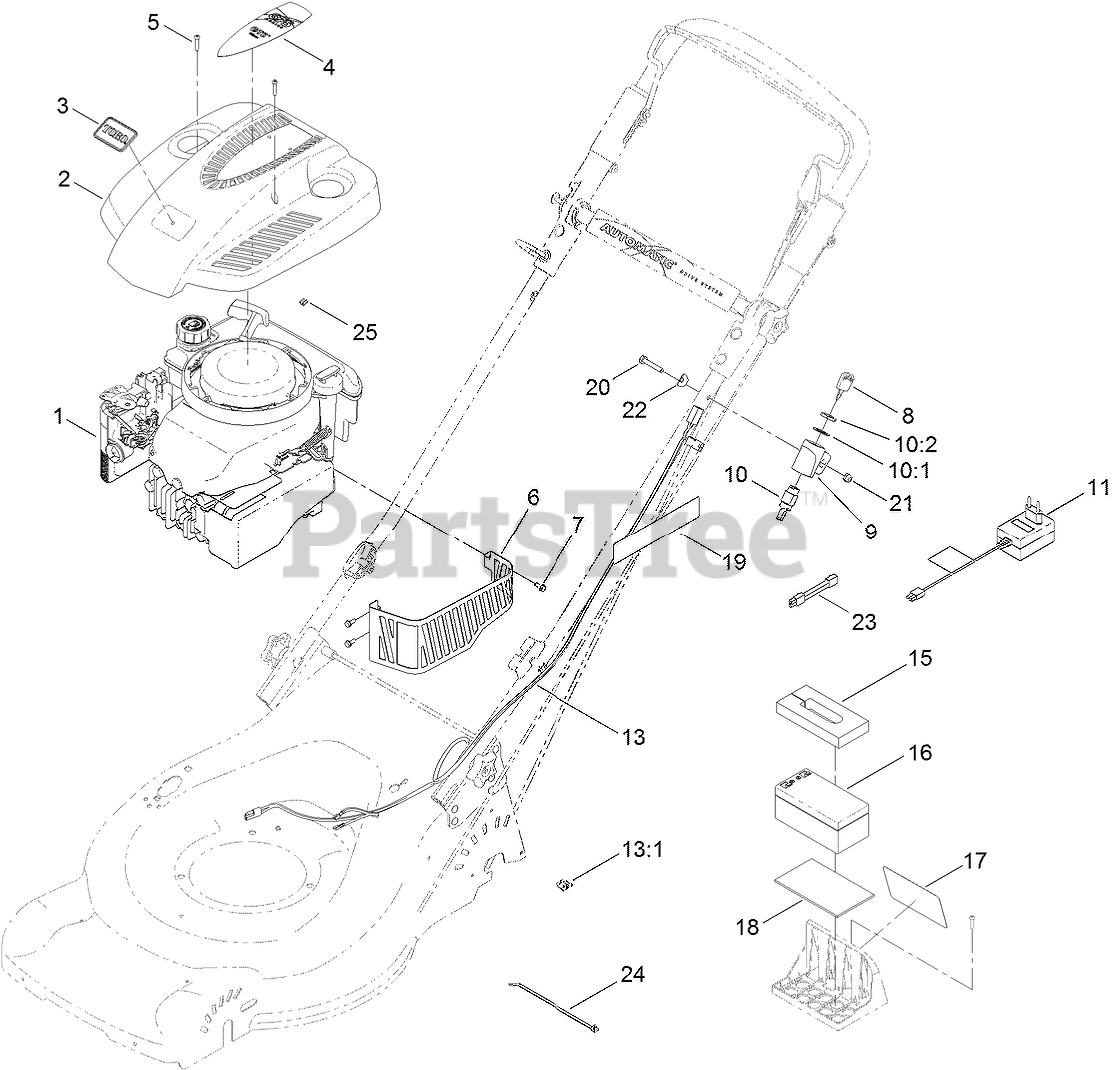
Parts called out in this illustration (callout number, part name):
2	SHROUD-ENGINE
3	PLATE-LOGO
4	DECAL-ENGINE, 48CM
5	SCREW-PPH
6	SHIELD-MUFFLER
7	SCREW-TAPTITE
9	MOUNT-SWITCH
10	STARTER SWITCH ASM
10:1	WASHER-TOOTH, INTERNAL
10:2	NUT-HH
11	CHARGER-EUROPEAN, 12V DC
13	HARNESS-WIRE, WPM
13:1	FUSE-40 AMP
15	FOAM-BLOCK
16	BATTERY-WET
17	DECAL-FUSE
18	FOAM-BATTERY
19	DECAL-WARNING
20	SCREW-HH
21	NUT-LOCK, NI
22	WASHER
23	ADAPTER-CHARGER
24	TIE-CABLE
25	STOP-ROPE
